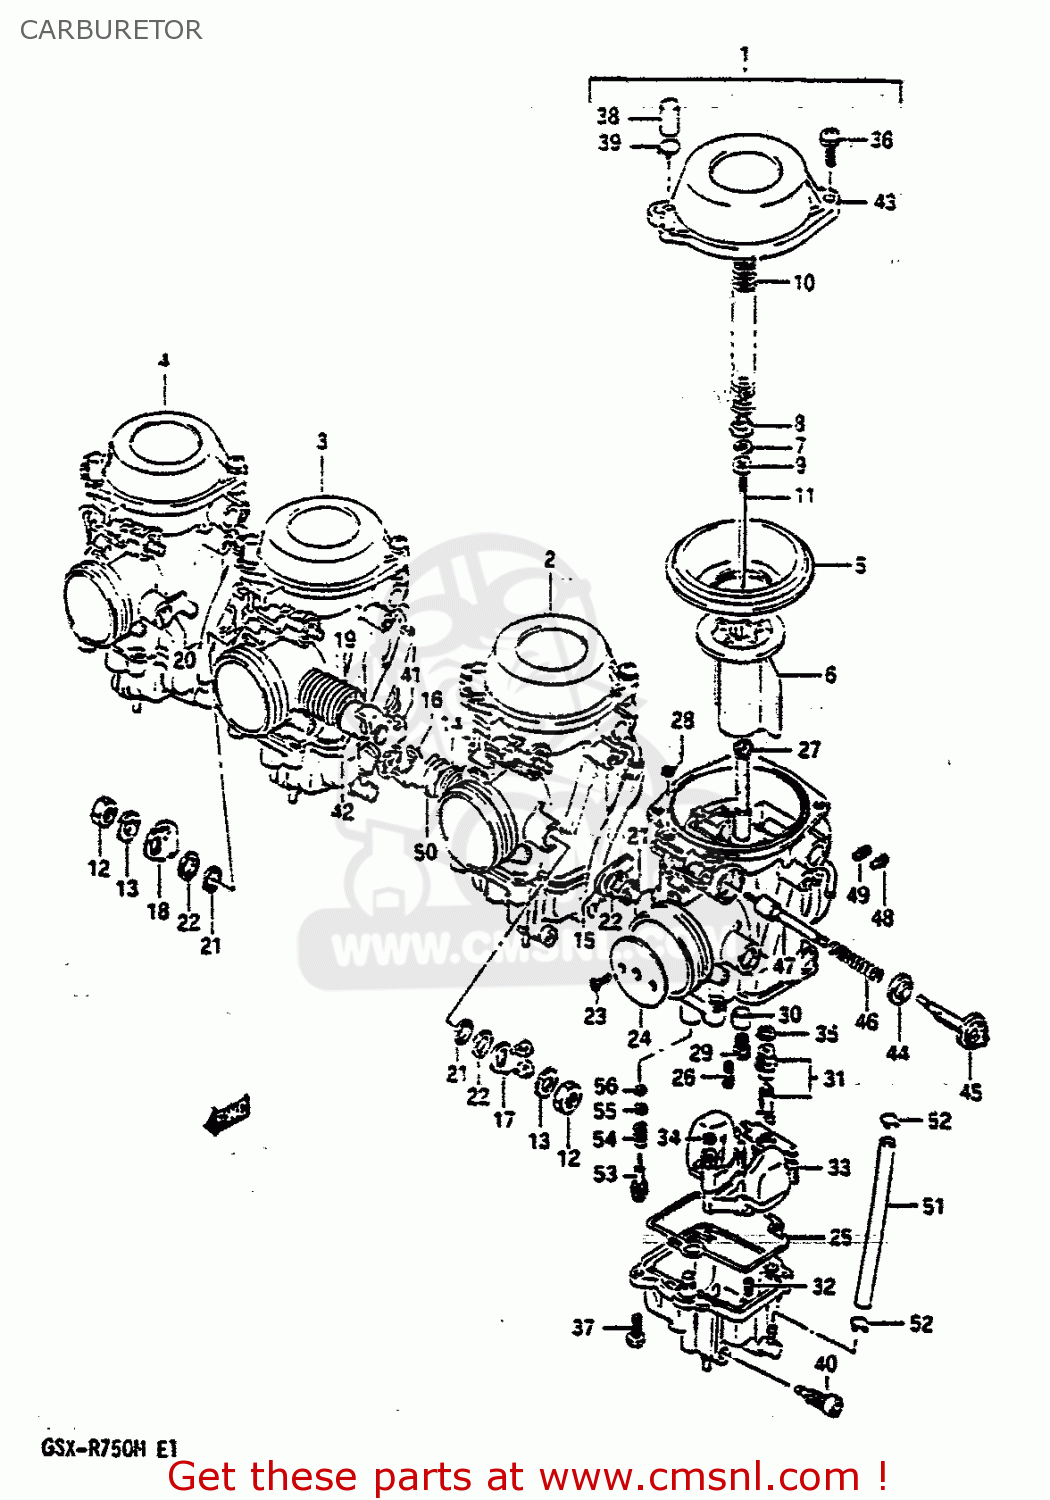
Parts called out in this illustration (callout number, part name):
1	CARBURETOR ASSY,LH
2	CARBURETOR ASSY,ML
3	CARBURETOR ASSY,MR
4	CARBURETOR ASSY,RH
5	DIAPHRAGM
6	VALVE,PISTON
7	CLIP,NEEDLE
8	9-1
9	RING
10	SPRING
11	NEEDLE,JET
12	NUT
13	WASHER,LOCK,8.
14	SPRING
15	SHAFT ASSEMBLY
16	SHAFT ASSEMBLY
17	LEVER
18	LEVER,THROTTLE
19	SPRING
20	SHAFT ASSEMBLY
21	SEAL
22	GASKET,THROTTLE SHAFT (NAS)
23	SCREW
24	VALVE,THROTTLE
25	GASKET,FLOAT CHAMBER (NAS)
26	JET,PILOT(35)
27	JET,NEEDLE(O-8)
28	O RING
29	JET,MAIN
30	RING
31	VALVE ASSEMBLY,NEEDLE
32	PLUG
33	FLOAT ASSY
34	O RING
35	O-RING,NEEDLE VALVE
36	SCREW
37	SCREW
38	CAP
39	CLIP
40	PLUG,DRAIN
41	SHAFT ASSEMBLY
42	RING
43	COVER,DIAPHRAGM
44	CAP,STARTER
45	HOLDER,GUIDE
46	SPRING
47	PLUNGER ASSY
48	JET,AIR(1.2)
49	JET,AIR(1.2)
50	RING
51	HOSE
52	CLIP
53	SCREW,PILOT
54	SPRING
55	WASHER
56	O RING,PILOT AIR SCREW
